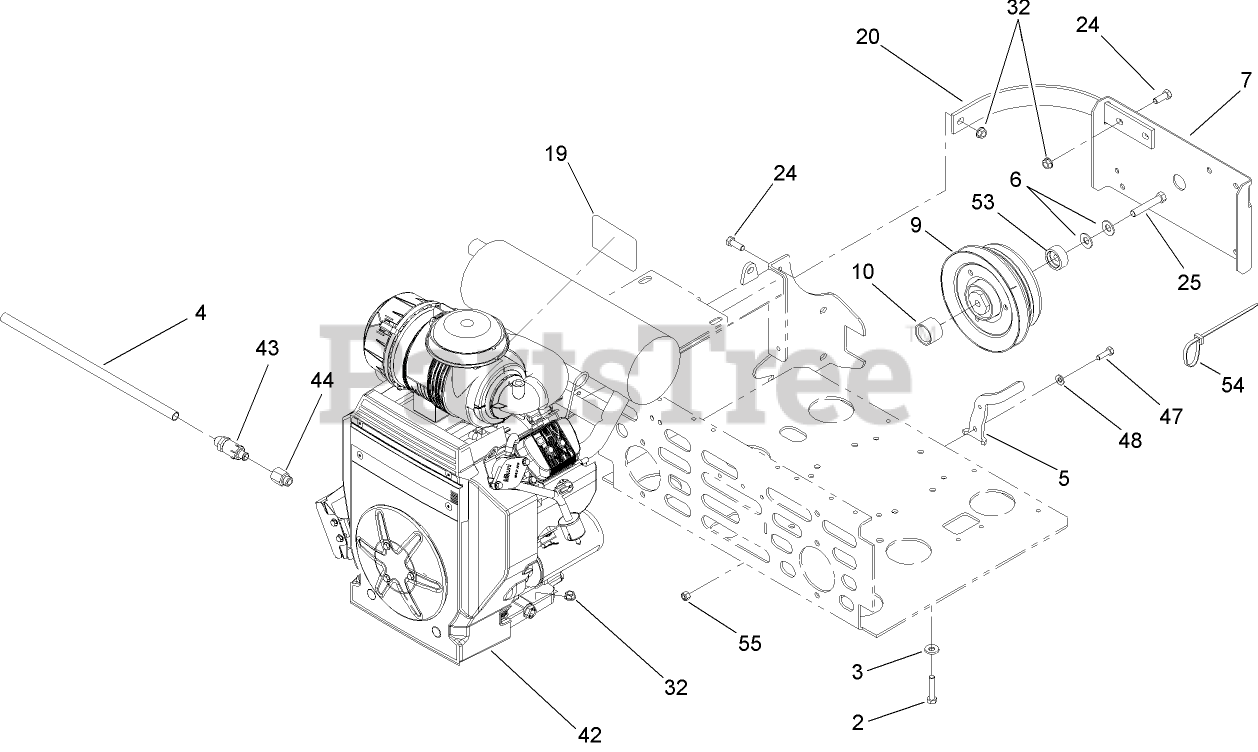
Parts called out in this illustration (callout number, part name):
2	SCREW-HH
3	WASHER-BELLEVILLE
4	TUBE-DRAIN, OIL
5	ANCHOR-CLUTCH
6	WASHER-SPRING
7	GUARD-CLUTCH
9	CLUTCH
10	SPACER-CLUTCH
20	STRAP-GUARD
24	SCREW-HH
25	SCREW-HH
32	NUT-HHF, WHIZ
43	VALVE-DRAIN, OIL
44	Adapter
47	SCREW-HH
48	WASHER-SPRING
53	KEEPER-CLUTCH
54	TIE-PLASTIC
55	NUT-LOCK, NI
